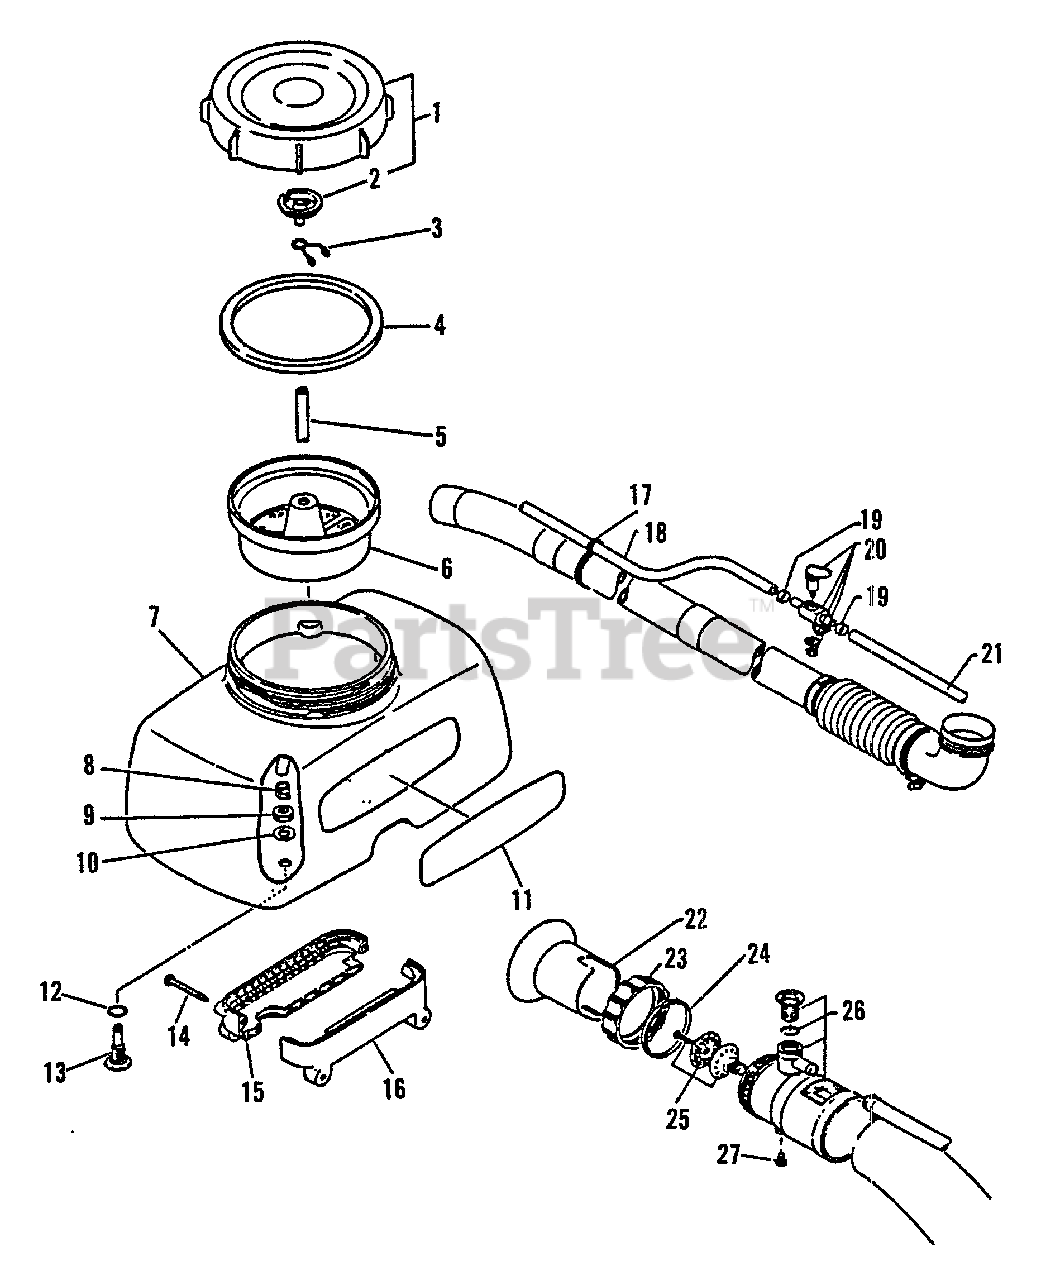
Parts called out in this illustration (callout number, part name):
1	CAP, CHEMICAL TANK
2	CONNECTOR, PIPE
3	CLAMP
4	GASKET, CHEMICAL TANK
5	PIPE, INNER PRESSURE 7×11×400BL
7	TANK, CHEMICAL
8	CLAMP
10	WASHER 12×20×1
11	LABEL - ECHO
12	O-RING 16 MM
13	CONNECTOR, PIPE
14	SCREW 5×50
15	HOLDER, TANK
16	HOLDER, TANK
17	CLIP
19	CLIP - 14
20	VALVE ASSY
21	HOSE
22	COLLAR, NOZZLE
24	RING, NOZZLE
25	NOZZLE ASSY
26	ADJUSTER, VOLUME
27	SCREW 5×12
